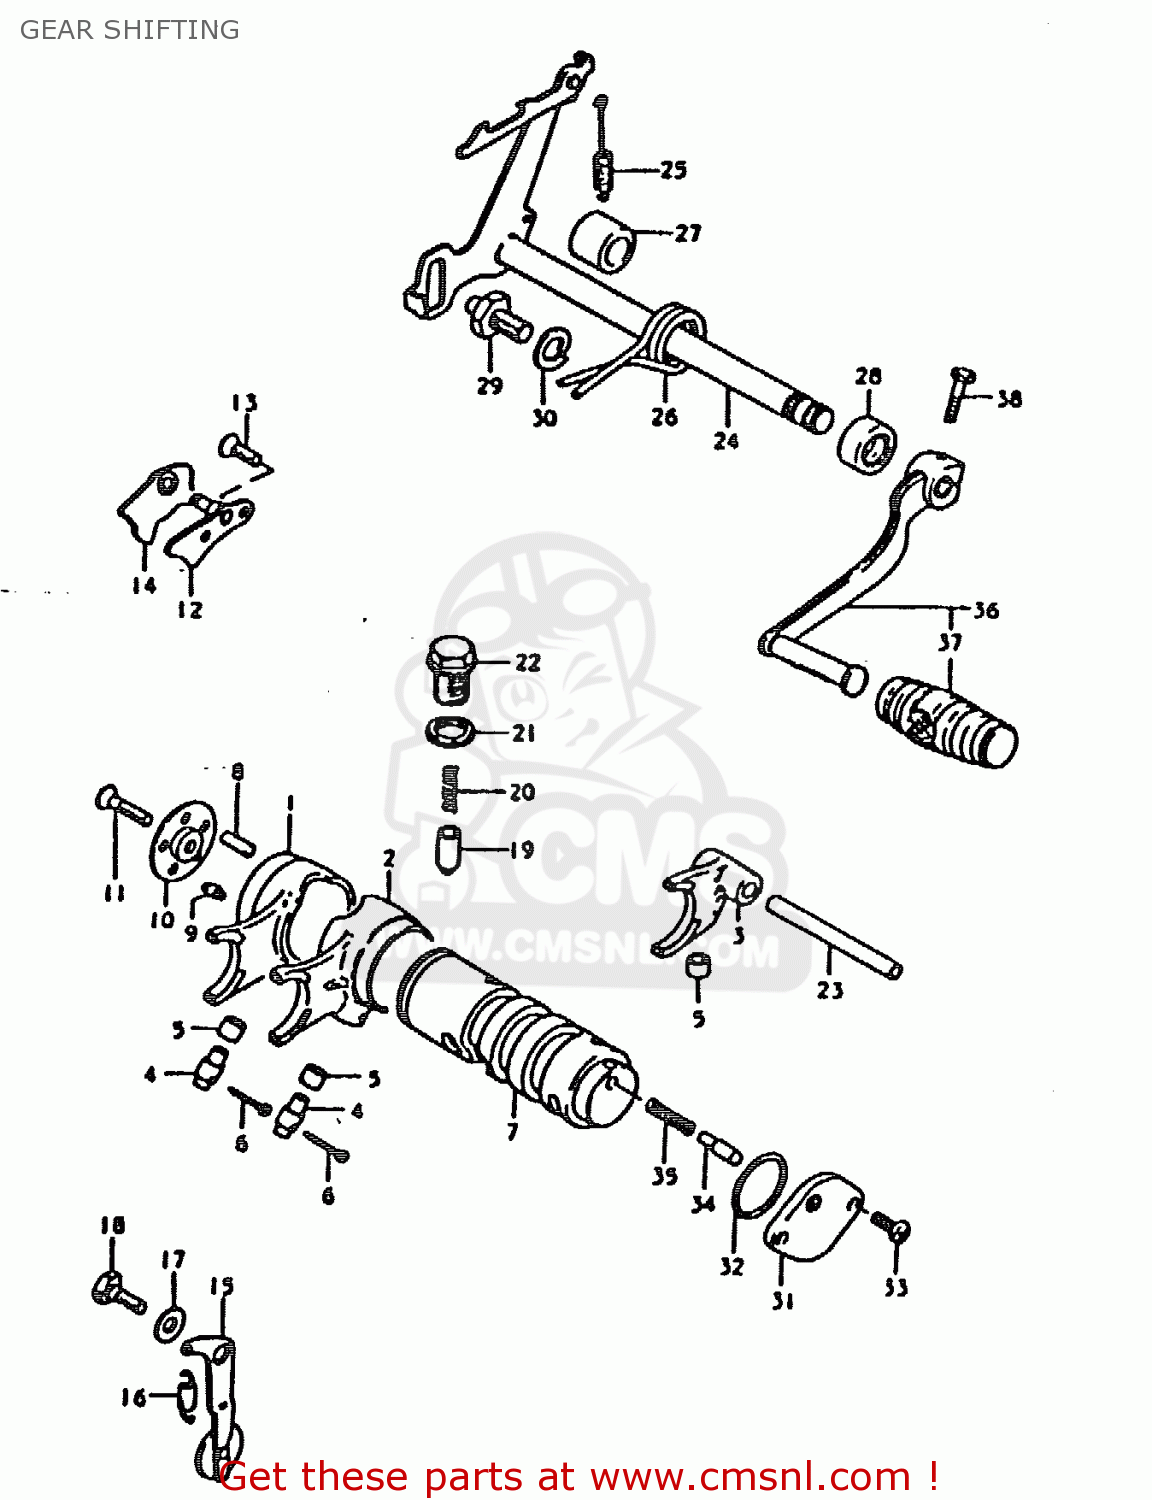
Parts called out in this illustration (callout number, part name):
1	FORK,GEAR SHIFT NO.1
2	FORK,GEAR SHIFT NO.2
3	FORK,GEAR SHIFT NO.3
4	PIN
5	SPACER
6	PIN 25X20
7	CAM,GEAR SHIFT
8	ROLLER(4X13.8)
9	PIN
10	RETAINER,GEAR SHIFT CAM DR PIN
11	SCREW
12	GUIDE,GEAR SHIFT CAM
13	SCREW
14	PAWL,GEAR SHIFT CAM STOPPER
15	STOPPER,GEAR SHIFT CAM
16	SPRING
17	WASHER(6.5X16X2.3)
18	BOLT(6X16.1)
19	STOPPER,GEAR SHIFTING
20	SPRING
21	GASKET(14X19.2X2) (NAS)
22	BOLT,GEAR SHAFT CAM STOPPER
23	SHAFT,GEAR SHIFT FORK
24	SHAFT,GEAR SHIFT
25	SPRING
26	SPRING
27	SPACER(12X20X15.3)
28	OIL SEAL
29	STOPPER,GEAR SHIFT ARM
30	WASHER
31	BODY,GEAR SHIFT SWITCH
32	O-RING (D:2.4 ID:26.2)
33	SCREW
34	PIN(5X15.5)
35	SPRING
36	LEVER ASSY,GEAR SHIFT
37	RUBBER,GEAR SHIFT PEDAL
38	BOLT
